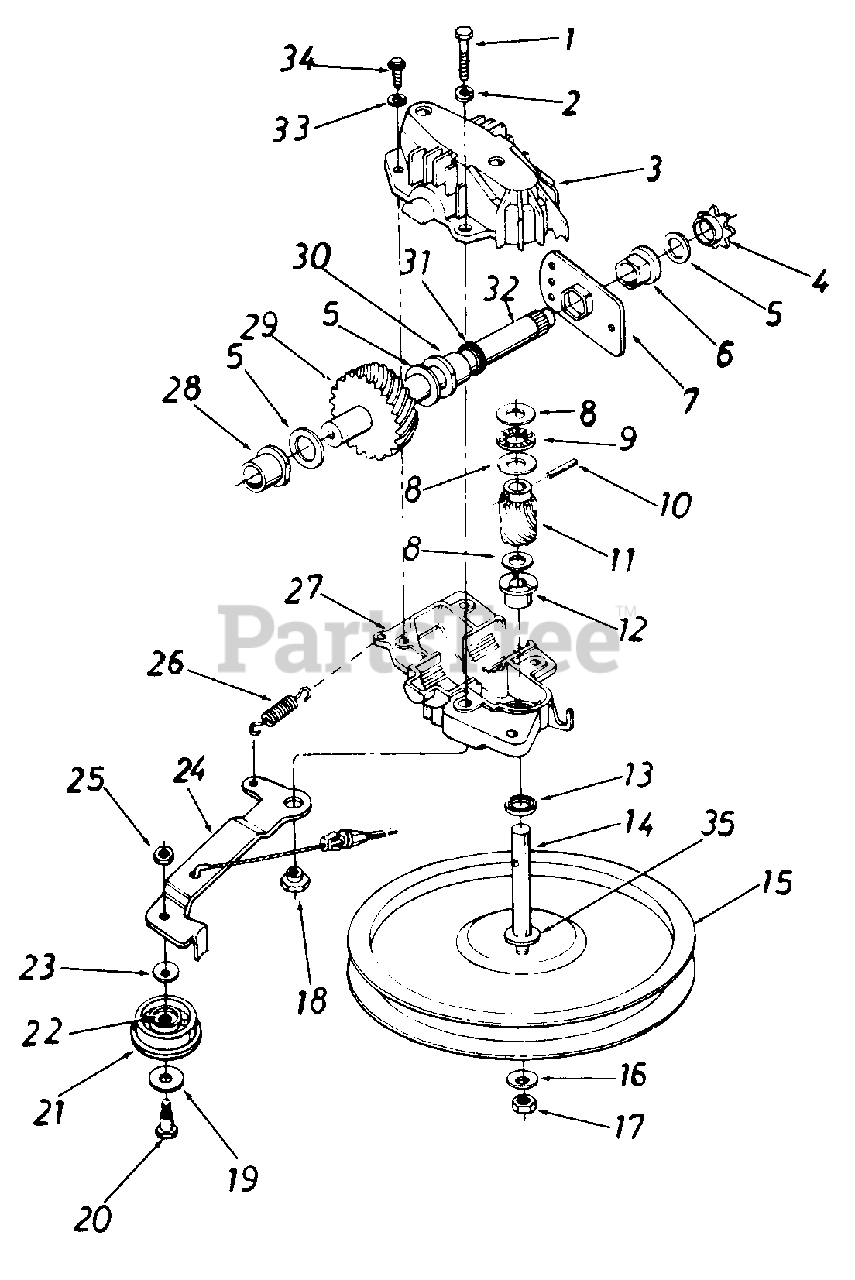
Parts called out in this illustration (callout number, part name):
1	Hex Bolt 1/4-20 x 1.25" Lg.
2	L-Wash. 1/4" I.D.
3	Upper Hsg. Half
4	#48 Sprocket 7 Tooth x 1/2 Pitch
5	Fl-Wash. 5/8" I.D. x .030
6	Hex Flange Brg. .631" I.D.
7	Hex Bearing Cup
8	Thrust Wash. .382" l.D. x .70" O.D.
9	Thrust Bearing .375" I.D. x .812" O.D.
10	Spring Pin Spir. 1/8" x .62" Heavy
11	11 Tooth Helical Gear
12	Flange Bearing
14	Pulley-Transmission Shaft
15	Fl-Pulley 5.06" O.D.
16	Bell-Wash. .265" I.D. x 75"
17	Hex L-Nut 1/4-28 L.H. Thd.
18	Shld. Spacer .3751' Dia. x .170
19	Fl-Wash. .3901' I.D. x 1.0"
20	Shld. Bolt .375" Dia. x .40"
21	Fl-ldler Plastic 1.50" Dia.
22	Needle Brg. .375'/ x .31
23	Bell-Wash. .265" I.D. x 75"
24	Idler Brk't. Ass'y
25	Hex Patch L-Nut 1/4-28 Thd.
26	Extension Spring 1.12" Lg.
27	Lower Hsg. Half
28	Flange Bearing .566 Dia.
29	33 Tooth Helical Gear
30	Flange Bearing .629 Dia.
31	Oil Seal .625 Dia.
32	Gear Sprocket Shaft
33	L-Wash. #10 I.D.
34	Hex B-Tap Scr. #10 x .62
35	Hex Washer .26" x .88'
